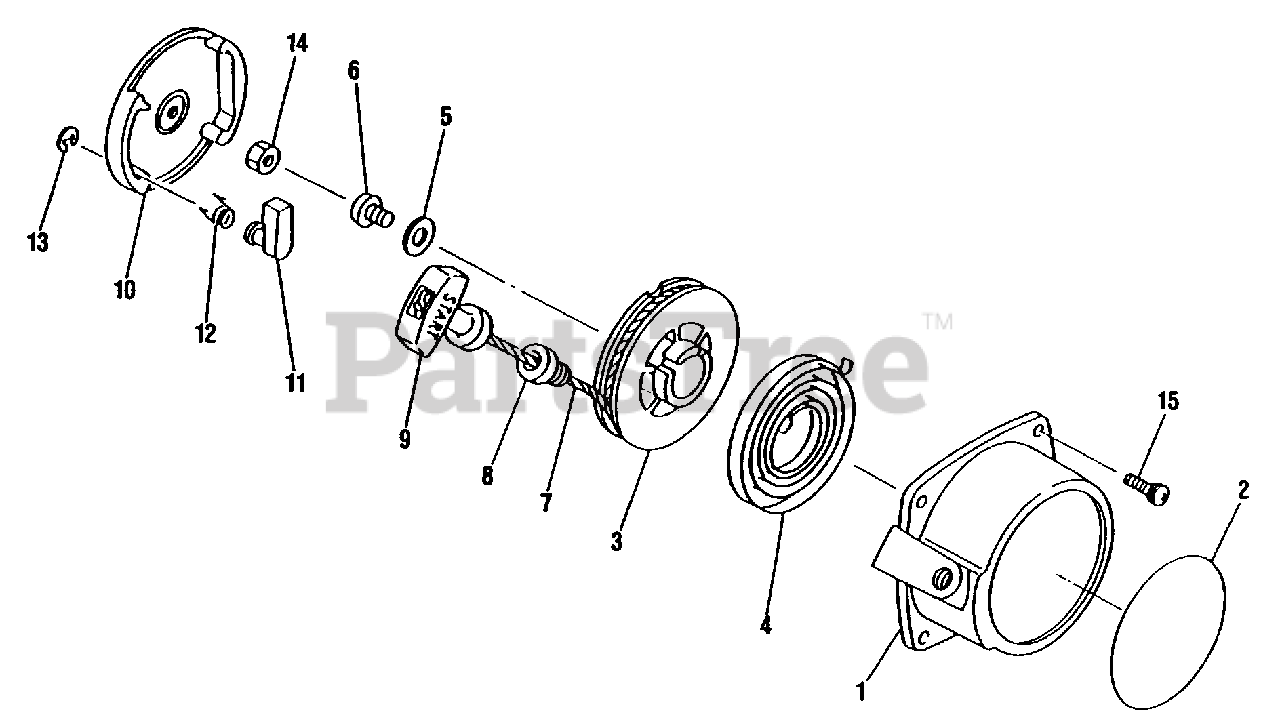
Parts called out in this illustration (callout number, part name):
1	CASE, STARTER
2	NAME PLATE
3	REEL, ROPE
4	SPRING, RECOIL
5	WASHER 5
6	SCREW 5
7	ROPE, STARTER
8	GUIDE, ROPE
9	GRIP, STARTER
10	PULLEY, STARTER
11	RATCHET
12	SPRING, RETURN
13	E-RING
14	NUT
15	SCREW
